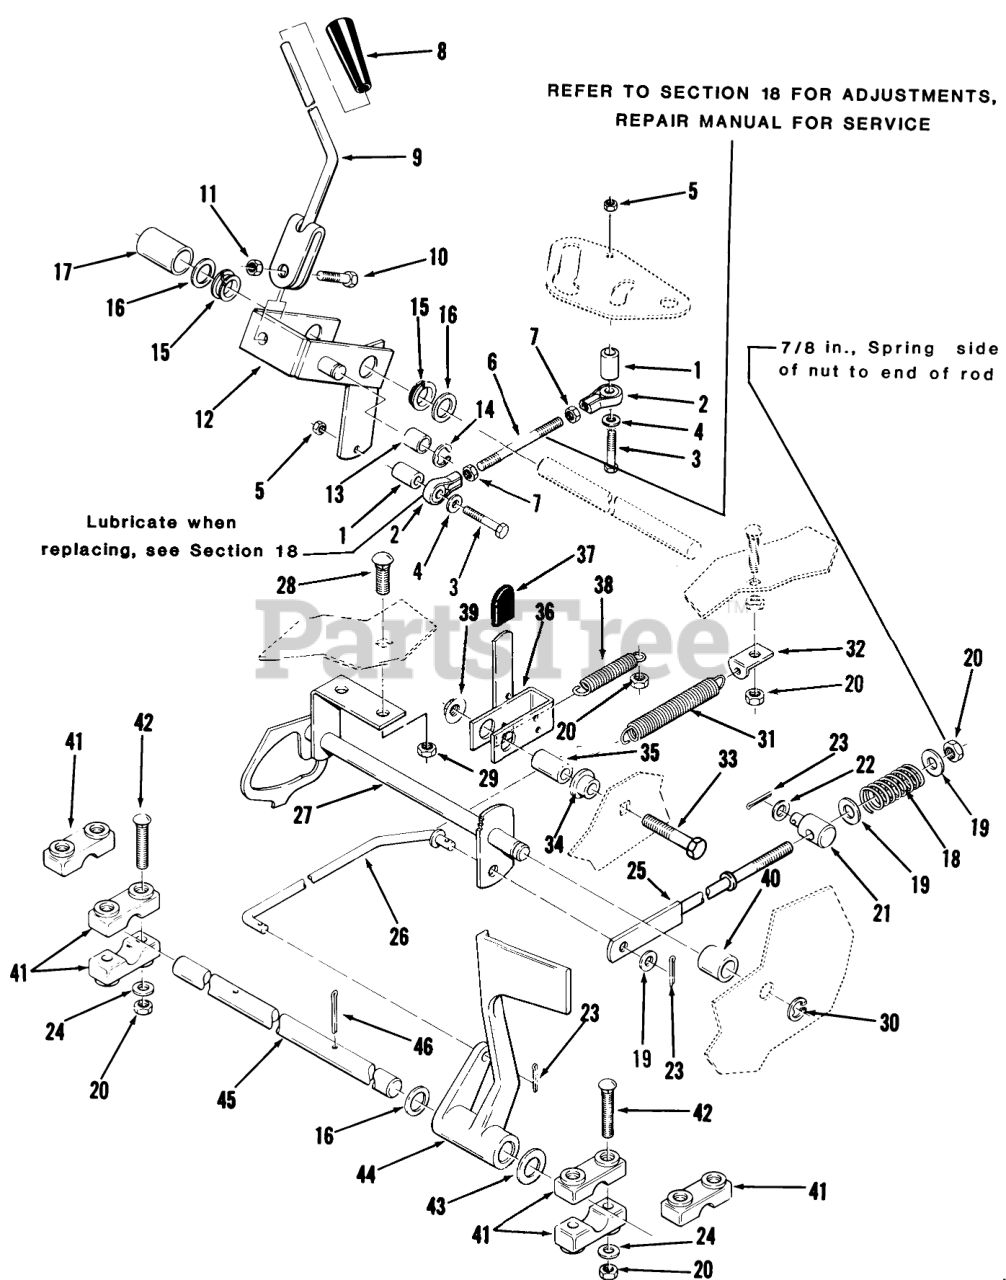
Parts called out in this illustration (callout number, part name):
1	Spacer
2	ASSY ROD END
3	Bolt 1/4-20 X 1 1/2
5	Nut
6	Control Rod
7	Jam Nut 1/4-28
8	KNOB
9	CONTROL ARM ASSY OBS
10	Bolt
11	NUT
12	Control Cam
13	BEARING-CAM RETURN
14	E Ring
15	Bushing
16	Washer
17	SPACER
18	SPRING FRICTION
19	Collar
20	Nut
21	TRUNNION-LIFT
22	Washer
23	Cotter Pin
24	WASHER 5/16 SAE
25	REAR BRAKE ROD ASM R
26	BRAKE ROD (FRONT)
27	ASSY NEUTRAL RETU R
28	Carriage Bolt 3/8-16 X 3/4
29	Nut
30	E Ring
31	CLUTCH SPRING
32	CLIP - SPRING
33	Bolt
34	SPACER
35	SPACER
36	Parking Brake Lever
37	GRIP
38	SPRING-EXTENSION
39	LOCKNUT-FLANGE
40	Spacer
41	BLOCK PIVOT
42	Washer
43	Special Washer
44	PEDAL CLUTCH R
45	Shaft
